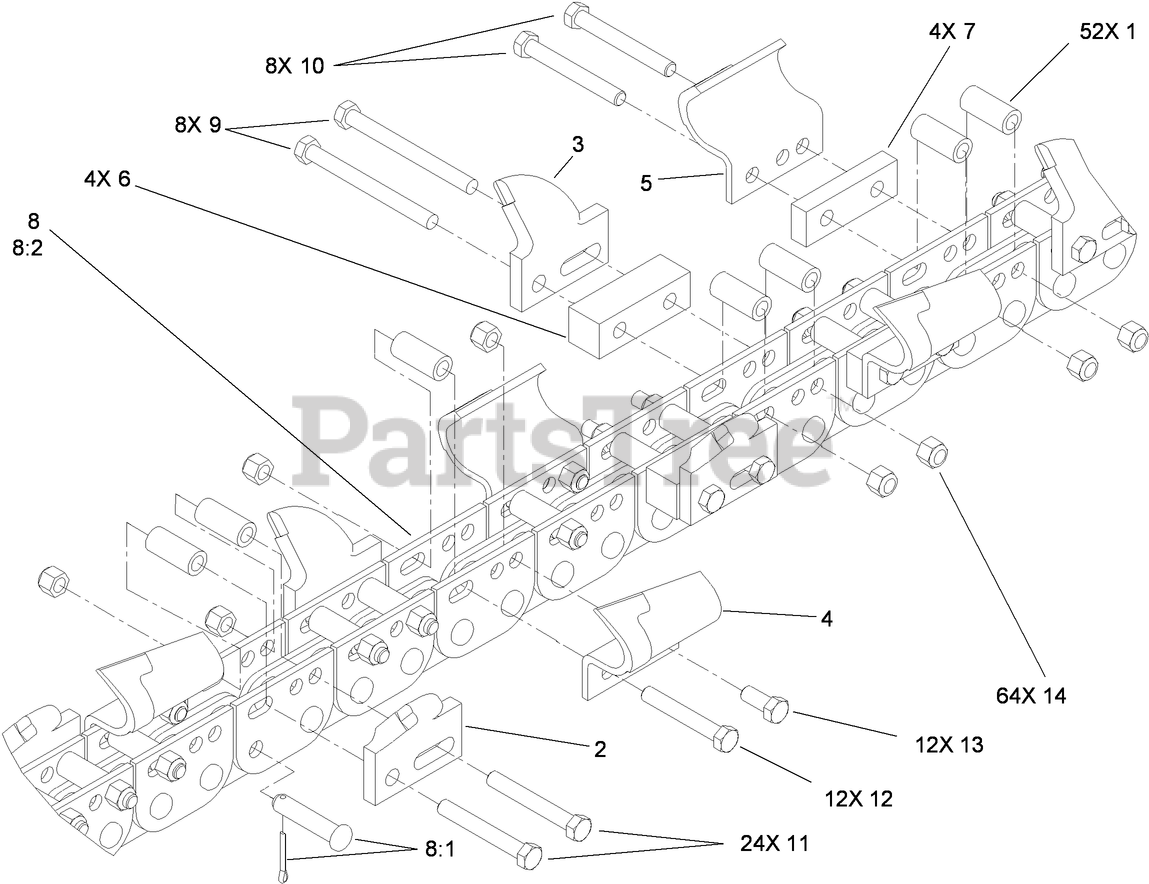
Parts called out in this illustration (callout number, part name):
1	SPACER-TUBE
2	TOOTH- ROCK, LH
3	TOOTH-ROCK, RH
4	TOOTH-SOIL, LH
5	TOOTH-SOIL, RH
6	SPACER-CUT, 6 INCH
7	SPACER-CUT, 5 INCH
8	CHAIN-BARE, 32 STATION
8:1	PIN-CONNECTING,
8:2	KIT-REPAIR, LINK
9	SCREW-HH
10	SCREW-HH
11	SCREW-HH
12	SCREW-HH
13	SCREW-HH
14	NUT-LOCK
